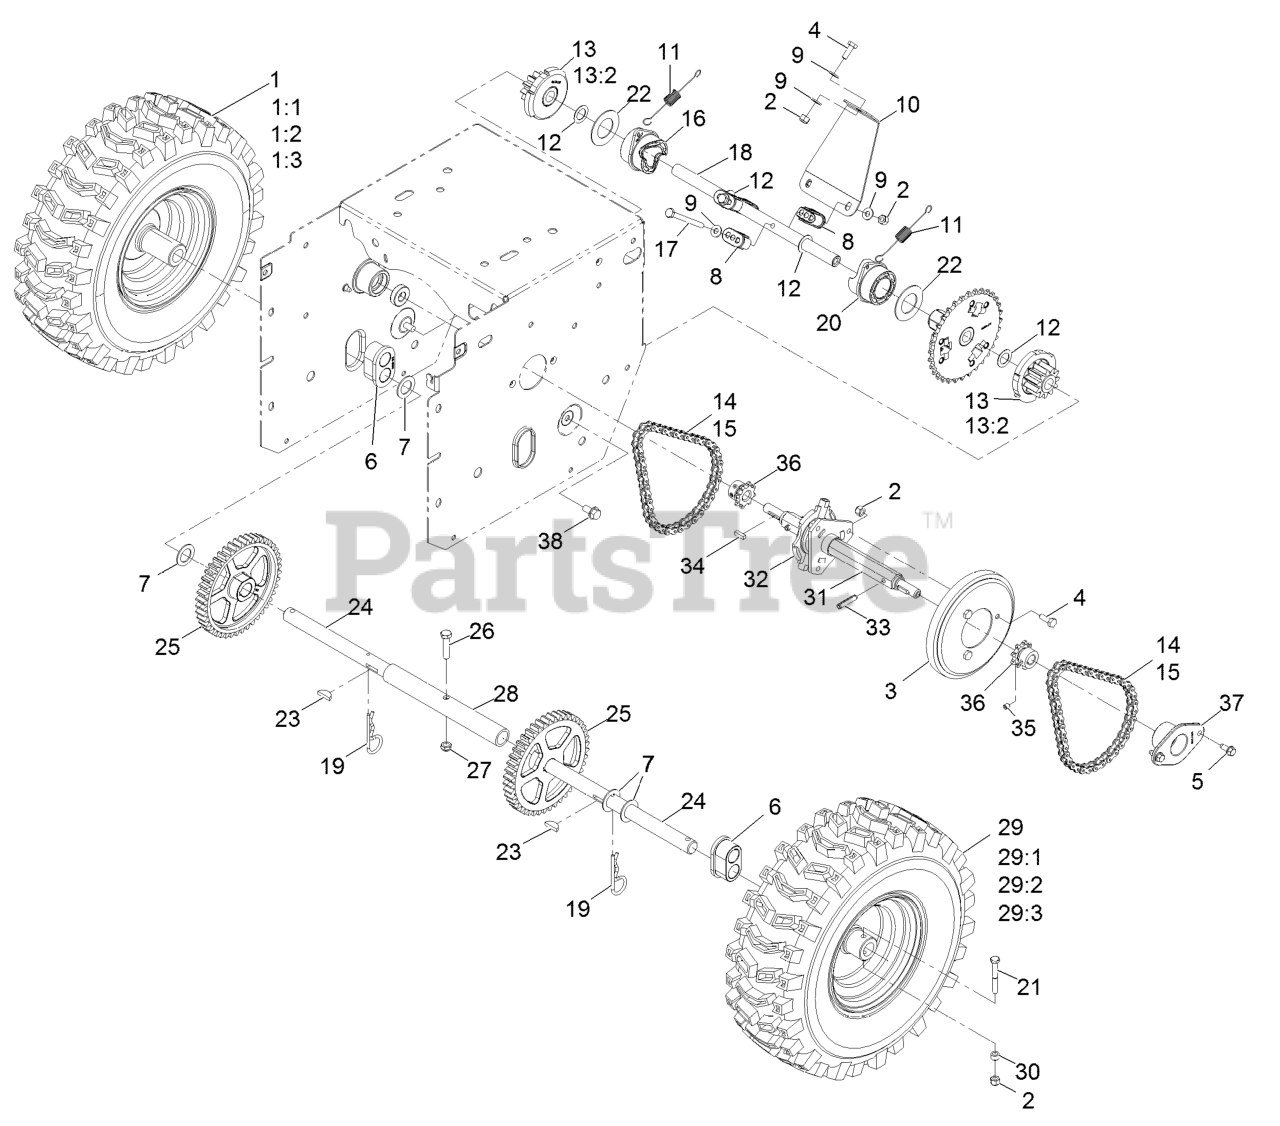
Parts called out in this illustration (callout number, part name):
1	Rh Wheel And Tire Asm
1:2	RIM-TIRE
1:3	Stem-Valve
2	NUT-LOCK, NI
3	WHEEL-FRICTION
4	SCREW-HH
5	SCREW-HWH
6	BEARING-AXLE
7	WASHER-THRUST
8	GUIDE-COLLAR
9	WASHER-FLAT
10	BRACE-COLLAR, SHIFT
11	SPRING-EXTENSION
12	WASHER-FLAT
13	11T GEAR ASM
13:2	BUSHING-FLANGE
14	CHAIN-ROLLER
15	LINK-CONNECTING
16	COLLAR-SHIFT, RH
17	SCREW-HH
18	SHAFT-INTERMEDIATE
19	PIN-HAIR
20	COLLAR-SHIFT, LH
21	SCREW-HH
22	WASHER-THRUST
23	KEY-WOODRUFF
24	SHAFT-AXLE
25	GEAR-AXLE, 44 TOOTH
26	SCREW-HH
27	NUT-LOCK, NI
28	TUBE-AXLE
29	Lh Wheel And Tire Asm
29:2	RIM-TIRE
29:3	Stem-Valve
30	SPACER-BLADE, ROTOR
31	SHAFT-HEX
32	TRUNNION-HEX
33	SCREW-HH
34	KEY-SQUARE
35	SCREW-HSH
36	SPROCKET-8 TOOTH
37	RETAINER-BEARING
38	SCREW-HWHTF
